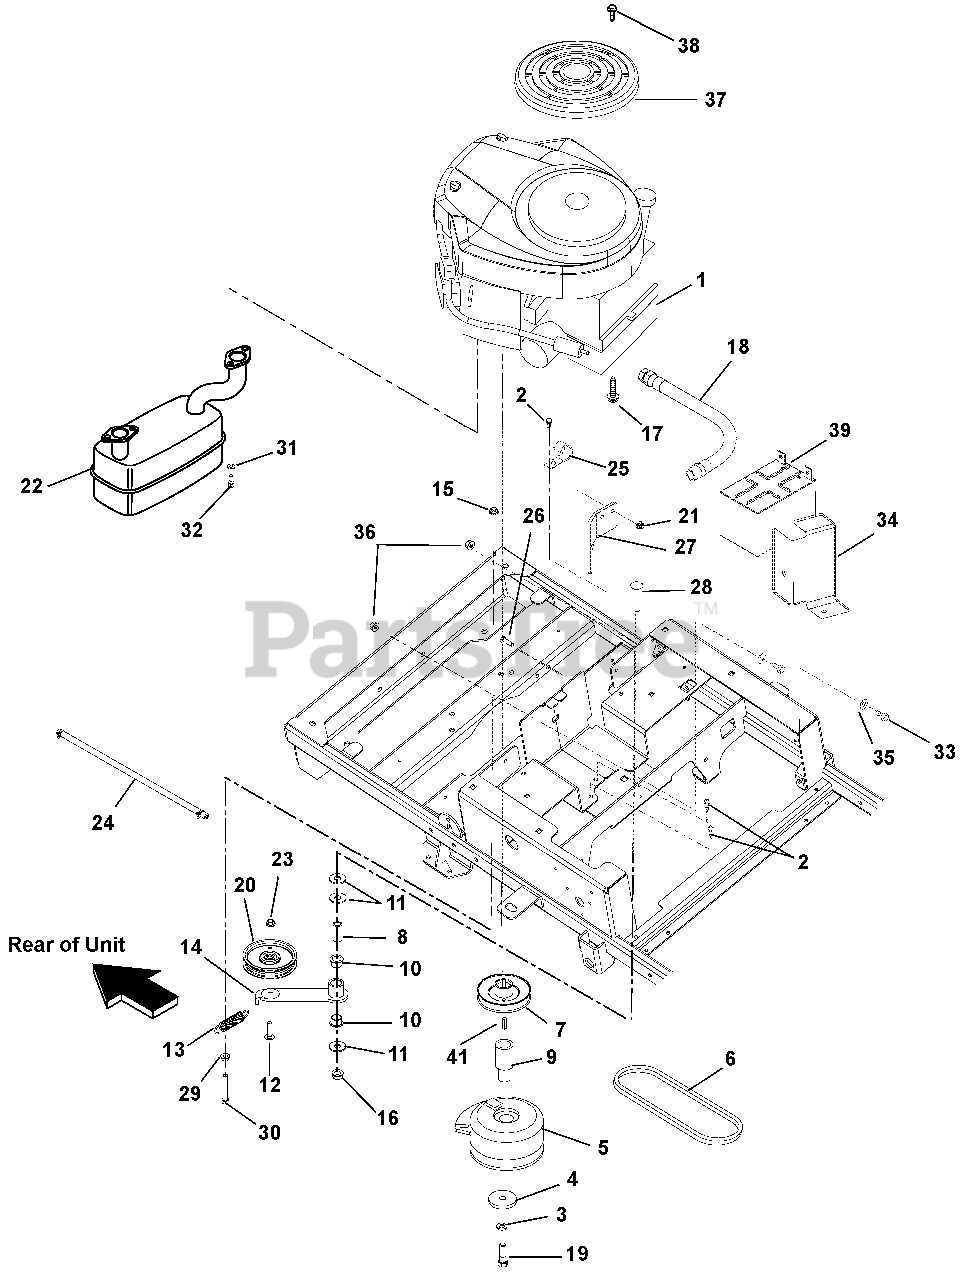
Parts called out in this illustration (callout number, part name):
1	ENGINE, 18HP V-TWIN CE
2	@SCR-TAP .25-20X.37 HWH YWZ TR
3	@WSHR-LK .44X.109 REG YWZC
4	WSHR-FL-STL .469X2.00X.25 YWZC
5	CLUTCH,105FTLB MONOPOLE 6.83"
6	V-BELT, HA-WRAPPED
7	PULLEY, V-1" ID X 4.50" OD
8	BSHG-SLV .500X.750X1.560
9	EXT-CRANKSHAFT LOWER
10	BSHG-FLG 0.75X0.875X.625X1.125
11	@WSHR-FL-STL.563X1.38X.109YWZC
12	@BLT-RDHDSQNK .38-16X1.50 G5YZ
13	SG-TENS .105X.812X3.88 WLD 15
14	WMT, GROUND DRIVE IDLER ARM
15	@NUT-LK-NYL-FLG .38-16 YWZC
16	@NUT-LK-TOP-FLG .50-13 YWZC
17	@SCR-TAP .38-16X1.00 HWH TR YZ
18	HOSE, HYD .38-11-0K M6N0-F6J0
19	BLT-HEX .44-20X4.50 GR8 YWZC
20	ASM, 4" IDLER (.75 WIDE)
21	@NUT-LK-NYL-FLG .31-18 YWZC
22	MUFFLER - TWIN BRIGGS
23	@NUT-LK-TOP-FLG .38-16 YWZC
24	HOSE, FUEL(CARB APPROVED)
25	J-CLAMP
26	@BLT-HEX .31-18X1.00 GR5 YWZC
27	CLUTCH STOP
28	@BLT-RDHDSQNK .50-13X2.50 G5YZ
29	@NUT-SPNLK-FLG .375-16 YWZC
30	@BLT-HEX .38-16X2.50 GR5 YWZC
31	@WSHR-LK .31X.078 REG YWZC
32	SCR-CAP .31-18X.75 S/HD
33	@BLT-HEX .25-20X.75 GR5 YWZC
34	BRKT, BATTERY HOLD DOWN
35	@WSHR-FL-STL.281X.62X.065 YWZC
36	NUT-KEPS .250-20
37	GUARD, BRIGGS ENGINE
38	SCREW, 8-16X.87 PHPAN 3 LOBE
39	BATTERY, 12V 12A-190CCA
40	CLAMP, FUEL LINE
41	KEY-STR .25X2.0X.25
